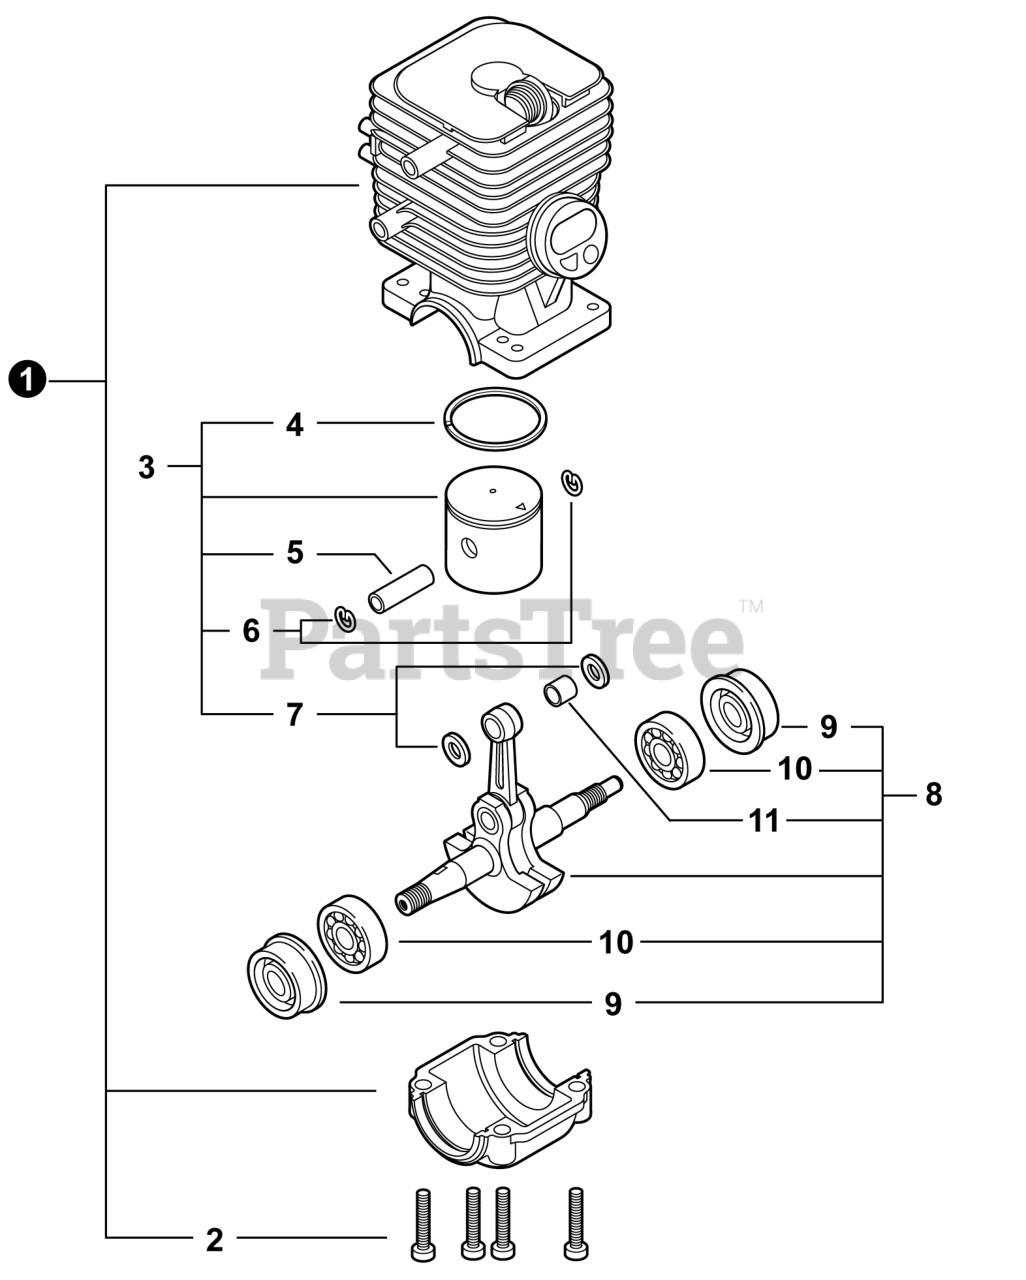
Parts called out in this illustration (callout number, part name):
1	CRANKCASE KIT
2	BOLT, TORX 5×25
3	PISTON KIT
4	RING, PISTON
5	PIN, PISTON
6	RING, SNAP
7	WASHER, THRUST
8	CRANKSHAFT ASSY
9	SEAL, OIL 12
10	BEARING, BALL 6201
11	BEARING, NEEDLE 8
